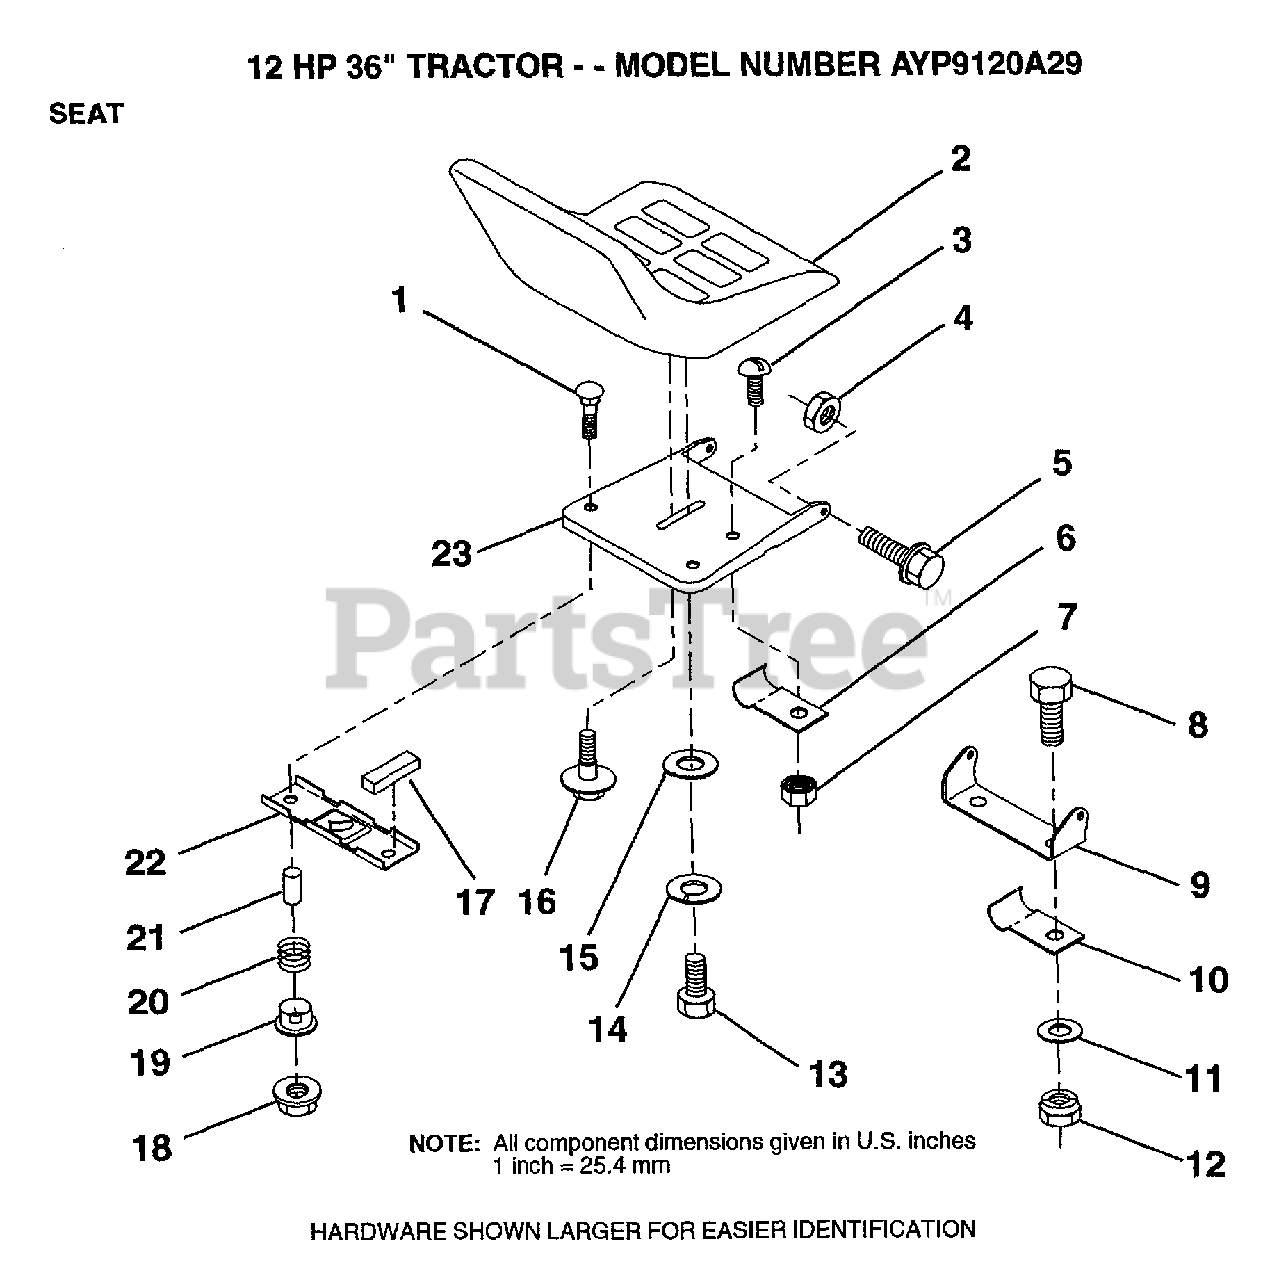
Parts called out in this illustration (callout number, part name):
7	"NUT,KEPS"
10	"CLIP,INSULATOR"
11	WASHER
12	NUT, CROWNLOCK
13	BOLT
14	LOCKWASHER
15	WASHER
16	"BOLT,SHOULDER"
17	STRIP FORM
19	BUSHING
20	SPRING
21	SPACER SPLIT
22	BRKT SWITCH
